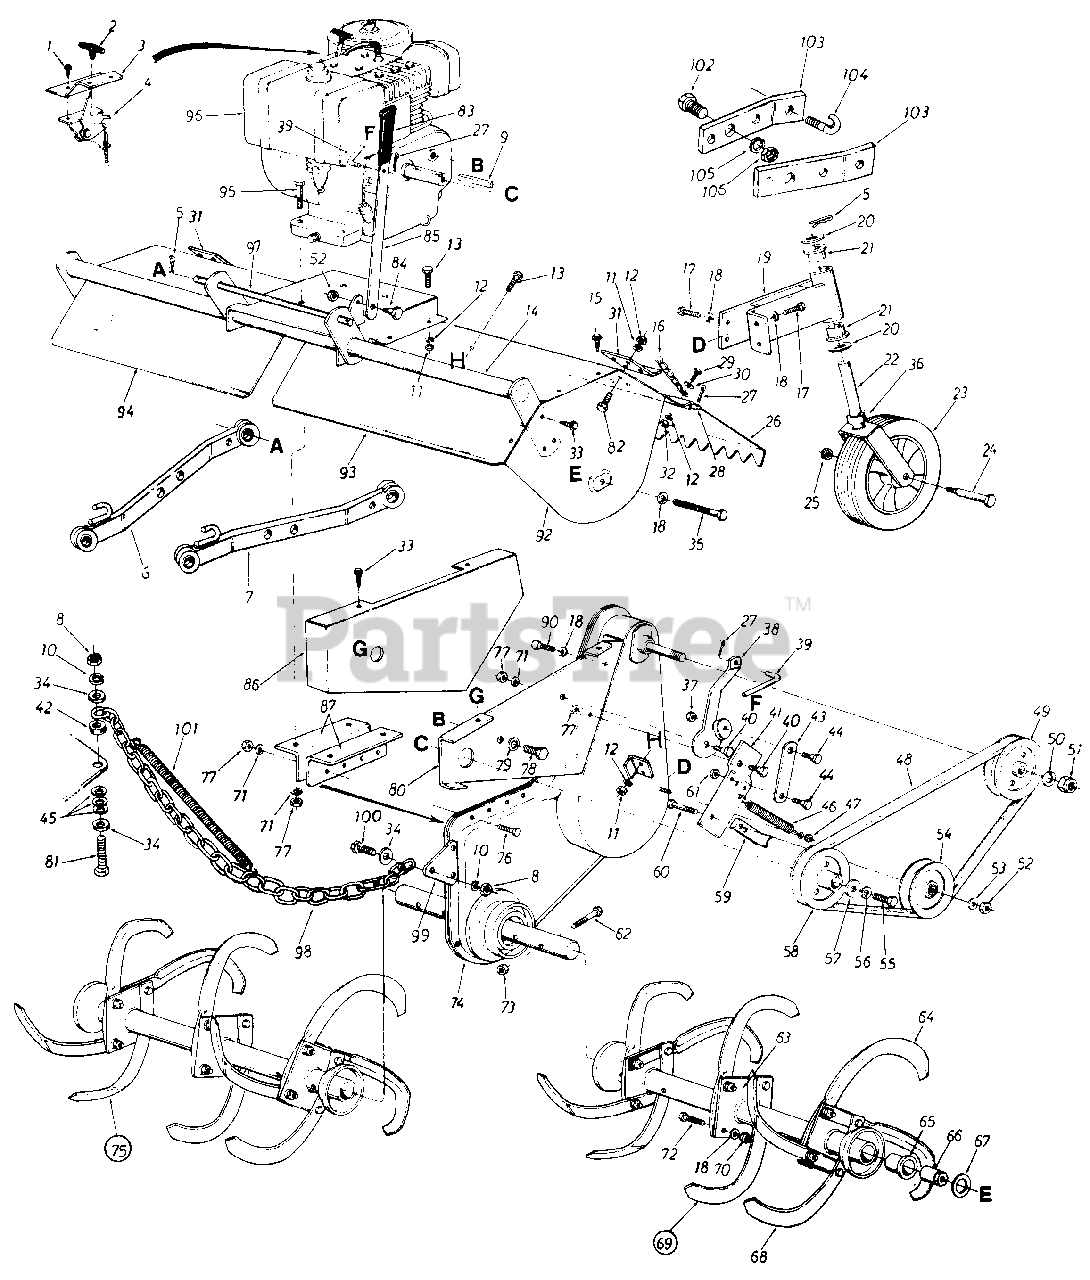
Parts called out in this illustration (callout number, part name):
1	Hex Wash. Hd. Self-Tap Scr. #8 x .50" Lg.
2	Throttle Control Knob- 0
3	Throttle Control Bracket
4	Throttle Control Ass'y. Comp.
5	Internal Cotter Pin
6	Draft Bar Ass'y.-R.H.
7	Draft Bar Ass'y.-L.H.
8	Hex Nut 3/8-24 Thd.*
9	Sq. Key 1/4" x 1/4" x 2.00" Lg.
10	L-Wash. 3/8" I.D.*
11	Hex Nut 1/4-28 Thd.
12	L-Wash. 1/4" I.D.
13	Hex Bolt 1/4-28 x .62" Lg.
16	#2 Dog Chain x 20" Lg.
17	Hex Wash. Hd. Self-Tap Scr. 3/8-24 x .75" Lg .
18	L-Wash. 3/8" I.D.*
19	Swivel Wheel Support
20	Fl-Wash. 3/4" I.D. x 1.50" O.D.
21	Flange Bearing 3/4" I.D. x 1.00" O.D.
22	Swivel Wheel Caster
23	Wheel Assembly 10.0 x 2.75
24	Shoulder Bolt .623" I.D. x 3.62" Lg.
25	Hex Cent. L-Nut 7/16-14 Thd.
28	L.H. Flap Rod
28	R.H. Flap Rod
29	Hex Bolt 1/4-20 x .62" Lg.
30	Fl-Wash. 1/4" I.D.
33	Hex Wash. Hd. Self-Tap Scr. 1/4" x .62" Lg.
34	Fl-Wash. .385" I.D. x 1.0" O.D. x .135 Thk.
35	Hex Bolt 3/8-16 x 1.25" Lg.
36	Spacer .752" I.D. x 1.25" O.D.
37	Hex Cent. L-Nut 5/16-18 Thd.
40	Shoulder Bolt 7/16" Dia. x 1.75" Lg.
45	Fl-Wash. .406" I.D. x .74" O.D. x .063 Thk.
46	Extension Spring .62" O.D. x 6.12" Lg.
47	Hex Crown Nut 3/8-24 Thd.
48	V-Belt 1/2" x 43" Lg. (Kevlar)
49	1/2" "V"-Pulley 4.75" O.D. x .625" Bore
50	L-Wash. 5/8" I.D.*
51	Hex Ins. L-Nut 5/8-18 Thd.
52	Hex Cent. L-Nut 3/8-16 Thd.
53	Fl-Wash. 3/8" I.D.
54	Idler Pulley 4.0" O.D.
55	Hex Bolt
56	L-Wash. 7/16" I.D.
57	Fl-Wash. 7/16" I.D. x 1.38 O.D.
58	1/2" "V"-Pulley .475" O.D. x 1.00" Bore
61	Hex Cent. L-Nut 5/16-18 Thd.
62	Hex Bolt 7/16-14 x 2.00" Lg.
65	Flange Bearing 1.00" I.D.
66	Spacer
67	Thrust Wash. 1/2" I.D. x 1.55" O.D.
68	Tine-R.H.
69	Tine Assembly Comp.-L. H .
70	Hex Nut 3/8-24 Thd.
71	L-Wash. 5/16" I.D.*
72	Hex Bolt 3/8-24 x 1.5" Lg.*
73	Hex Cent. L-Nut 7/16-14 Thd.
77	Hex Nut 5/16-18 Thd.*
78	Hex Bolt 1/2-20 x .88" Lg. (Grade 5)
79	L-Wash. 1/2" I.D.*
80	Clutch Support Bracket
81	Hex Bolt 3/8-24 x 1.75" Lg.
82	Hex Bolt 1/4-28 x .75" Lg.
83	Plastic Grip
84	Shoulder Bolt .498 Dia. x .212 Lg.
85	Clutch Handle
86	Clutch Support Shroud
87	Engine Mounting Bracket
90	Hex Bolt 3/8-16 x .62" Lg.
92	L.H.-Side Plate
96	8 H.P. Engine
97	Tiller Mounting Shaft 16" Lg.
98	Chain 23" Lg.
99	Tiller Mounting Bracket
100	Hex Bolt 3/8-24 x 1.25" Lg.
101	Extension Spring
102	Hex Bolt 5/8-18 x 1.62" Special
103	Drag Link Extension
104	Hitch Chain Hook
105	L-Wash. 5/8" I.D.*
106	Hex Jam Nut 5/8-18 Thd.
